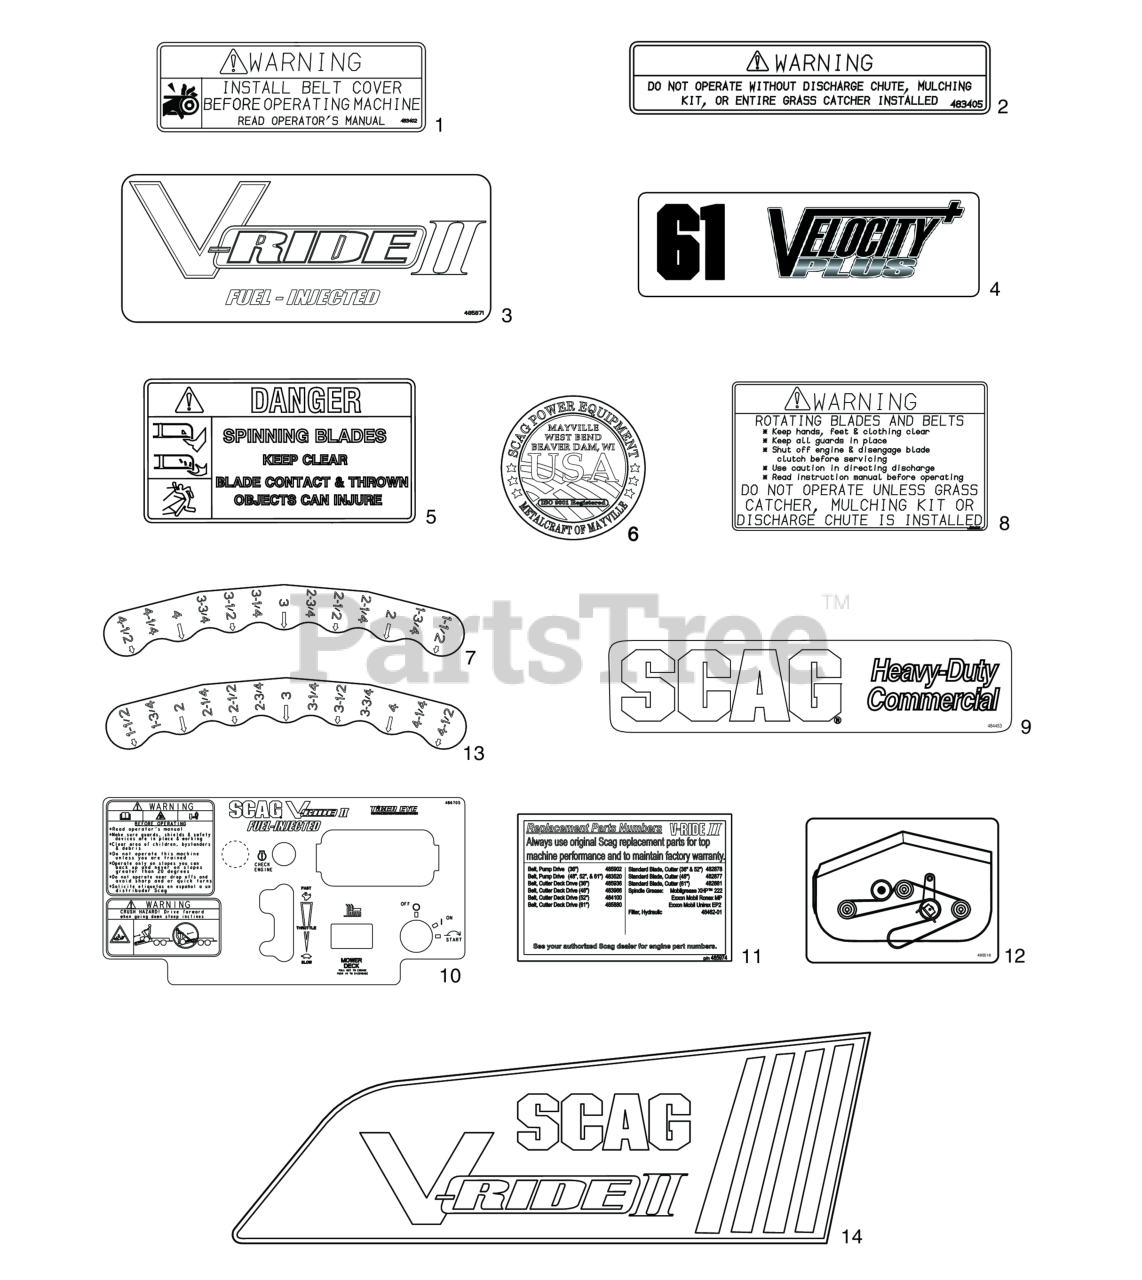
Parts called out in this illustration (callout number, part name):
1	Decal, Warning - Belt Cover
2	Decal, Warning-Discharge
3	Decal, Belt Cover
4	DECAL, VELOCITY PLUS - 48
5	Decal, Spinning Blades
6	Decal, Metalcraft - USA
7	Decal, Deck Height - Outer
8	Decal, Warning - Rotating Blades
9	Decal, Scag Heavy Duty Commercial
10	Decal, Instrument Panel - SVRII-EFI
11	Decal, SVRII Replacement Parts
12	Decal, Belt Routing - SVRII48V, SVRII52V & SVRII61V
13	Decal, Deck Height - Inner
14	Decal, Scag V-Ride II (Fuel Tank)
